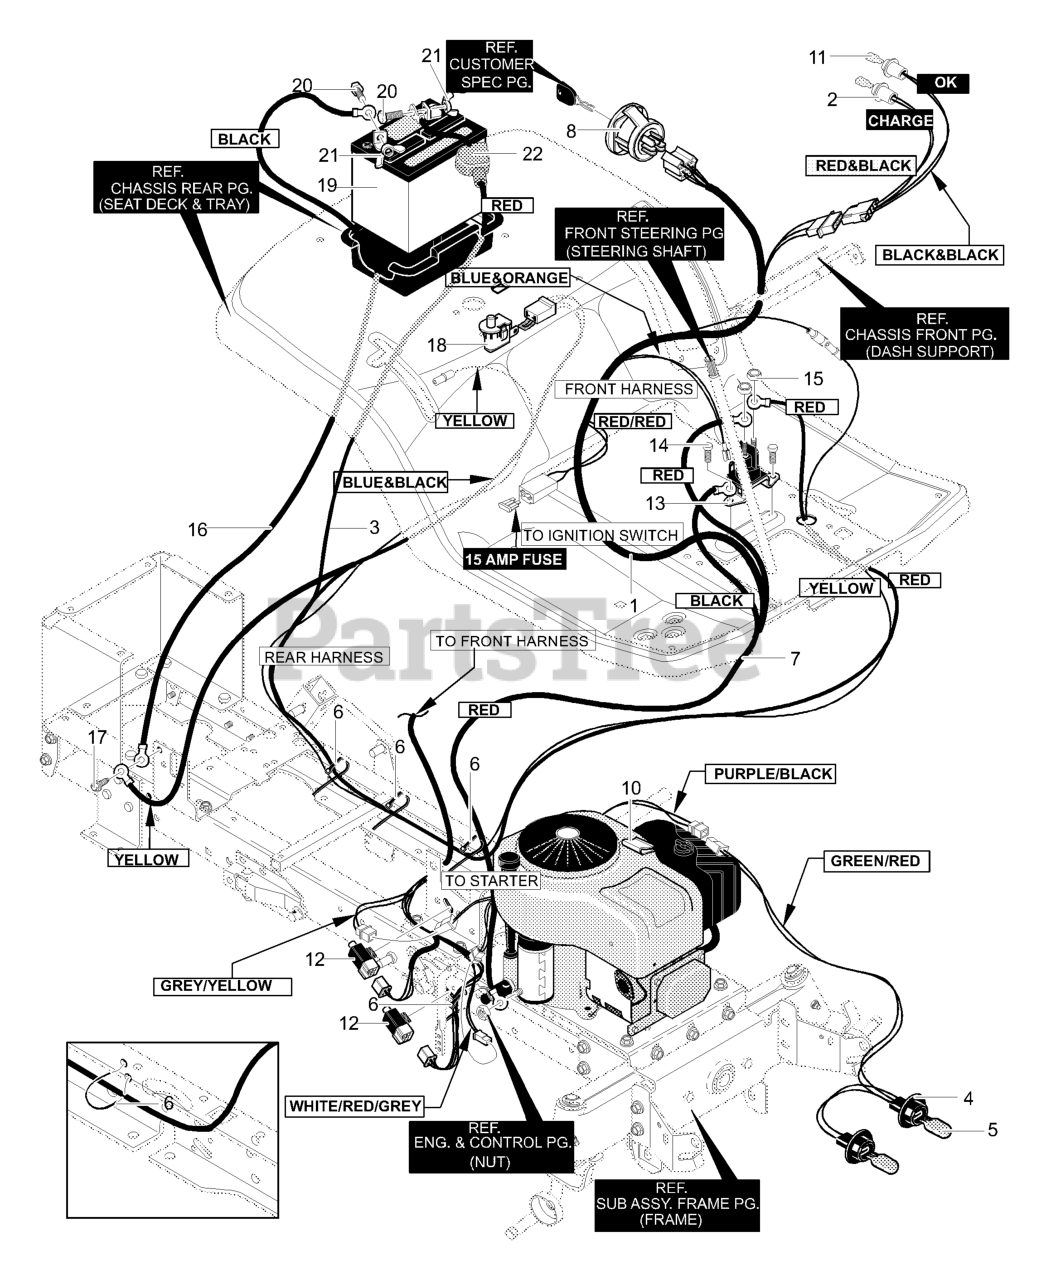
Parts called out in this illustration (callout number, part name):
1	Wire Harness w/Indicator
2	Harness, Ind. PTO/CHG
3	Wire Harness, Rear
4	Wire Harness *
5	Bulb, Headlamp
6	Cable Tie
7	Wire, Lead Solenoid to Starter
8	Switch, Ignition
10	Wire Clip, Adhesive
11	Bulb, Indicator
12	Switch, Limit
13	Solenoid
14	Screw 1/4x.50
15	Nut, 1/4-20
16	Ground Wire
17	Screw, 1/4x.75
18	Seat Switch
19	Battery 6 Plate
20	Bolt, 1/4-20x.63
21	Wing Nut
22	Battery Boot
